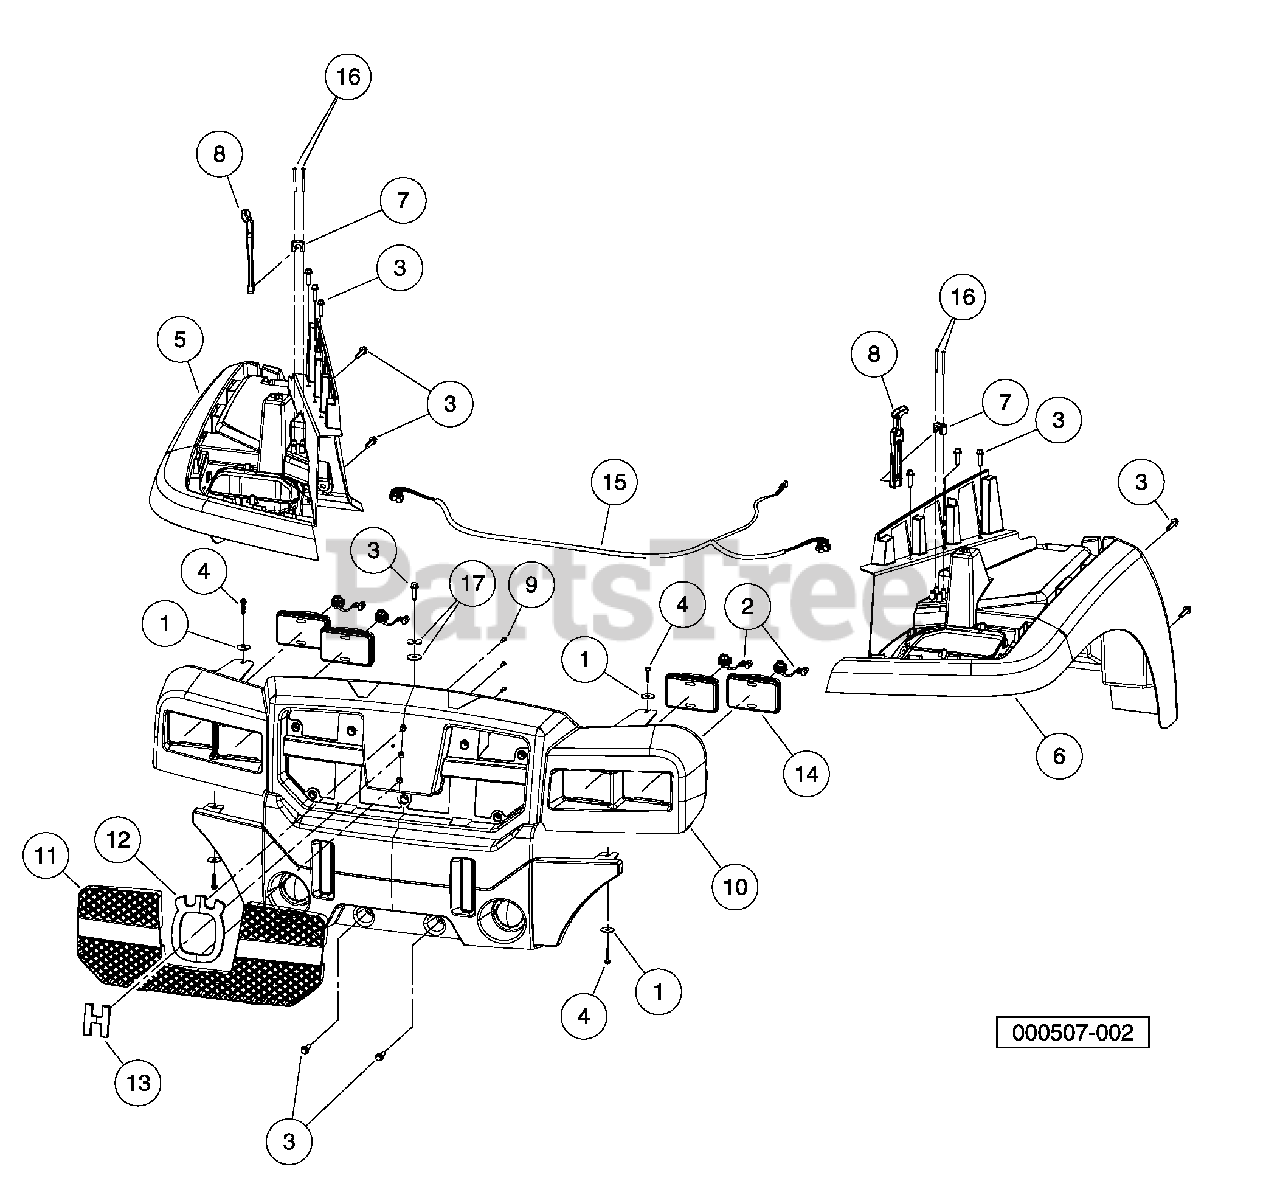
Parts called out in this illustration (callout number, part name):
1	Washer, 5/16 Type B Flat
2	Connector Harness Assembly, Headlight
3	Screw, M8X1.25X30, Hex
4	Screw,m6,torx,interlock,thread
5	Fender, Front, Pass, AWD
6	Fender, Front, Drv, AWD
7	Bracket, Latch, Draw
8	Latch, Draw, Hood
9	Screw, D50x16, Torx PN Hd PT
10	Fascia, Husqvarna
11	Grill, Husqvarna
12	Emblem, Husqvarna, Outer
13	Emblem, Husqvarna, Inner
14	Headlamp, 3x5 Rectangular
15	Harness, Bct/huv Restyle Headlight
16	Screw, #8x2.00 AB Thd, Hex Hd
17	Washer, 3/8 Type B Flat
